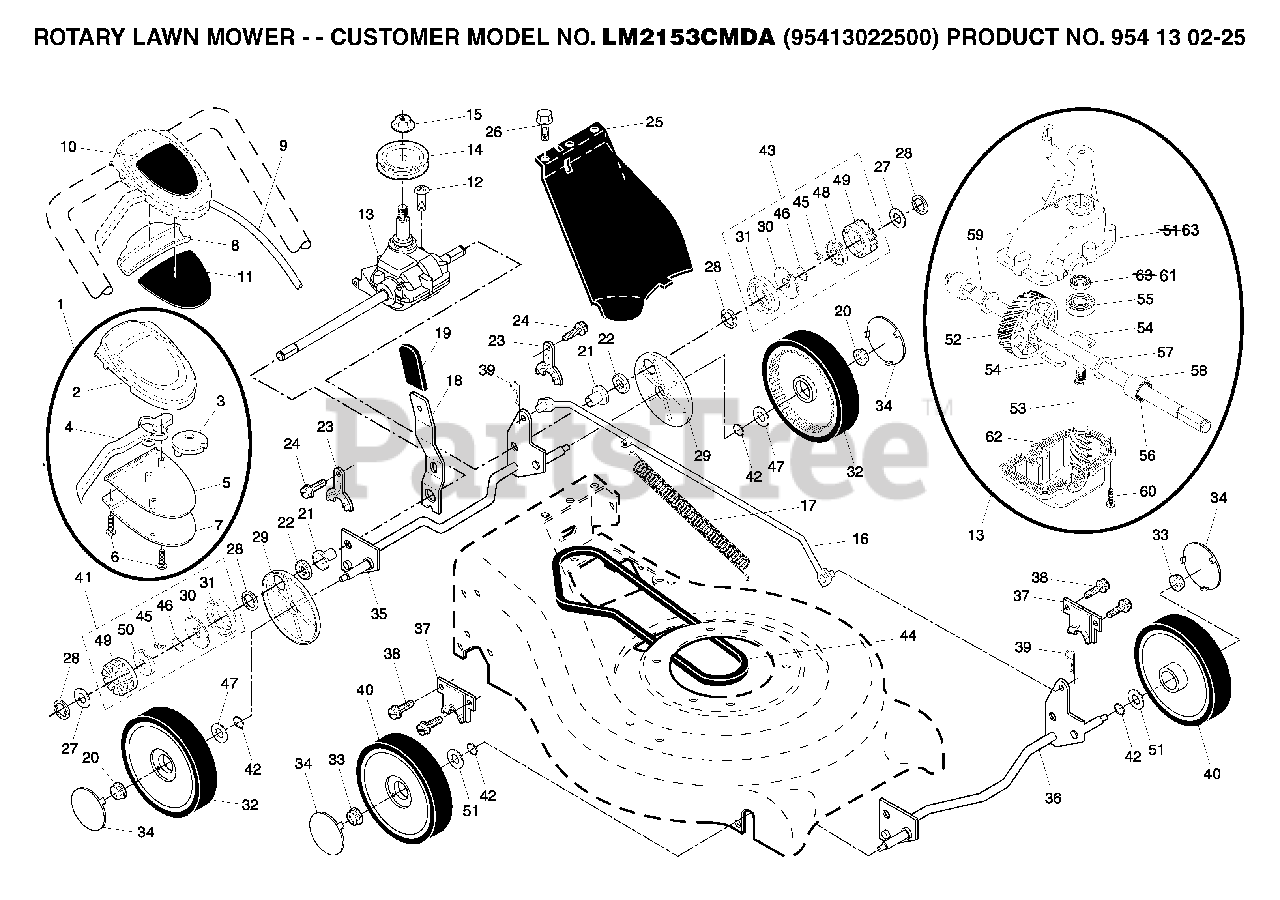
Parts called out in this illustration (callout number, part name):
3	PULLEY, DRIVE CONTROL
6	SCREW, PHILLIPS HEAD 10 X 5/8
7	BRACKET, DRIVE CONTROL
8	EA WLK COVER PLATE.BLK
9	CABLE, DRIVE CONTROL
13	TRANSMISSION.21.RWGD
14	RP PULLEY DRIVE
15	FLANGED LOCKNUT 3/8-16 ZINC
16	ROD CONNECTING
17	SPRING
18	SPRING.SELECTOR.SPT.21
19	KNOB, SELECTOR SPRING
20	NUT
21	RP BEARING SUPPORT
22	BEARING, BALL
23	BRACKET
27	WASHER
28	E-RING 7/16 RE
29	COVER.DUST.WHEEL
30	DISC.DRIVE.21.EZ-WALK
31	SEAL.PINION
32	WHEEL 9X2
33	HEX FLANGE LOCKNT
34	HUBCAP
35	SHAFT.ASM.REAR.TORQUE
36	SHAFT ASSY FRONT
37	RETAINER.FRONT.SHAFT
39	RETAINER CLIP
40	FRONT.WHEEL.8X2
41	PINION ASSY, RH
42	O-RING
43	PINION ASSY, LH
44	V-BELT
45	PAWL.DRIVE.21.EZ-WALK
46	SPRING, TORSION
47	WASHER FLUT
48	RETAINER.DRIVE.21.EZ-WALK.LT
49	GEAR, PINION
50	RETAINER, DRIVE, RH
51	WASHER PM
52	GEAR.24.TOOTH.WALK.MOWER
53	SHAFT INPUT
54	WIRE, FORMED
56	SEAL.OUTPUT.SHAFT
59	SHAFT.OUTPUT.RGD.VS/EZ
61	SEAL INPUT SHAFT
62	CASE, LOWER
63	CASE, UPPER
